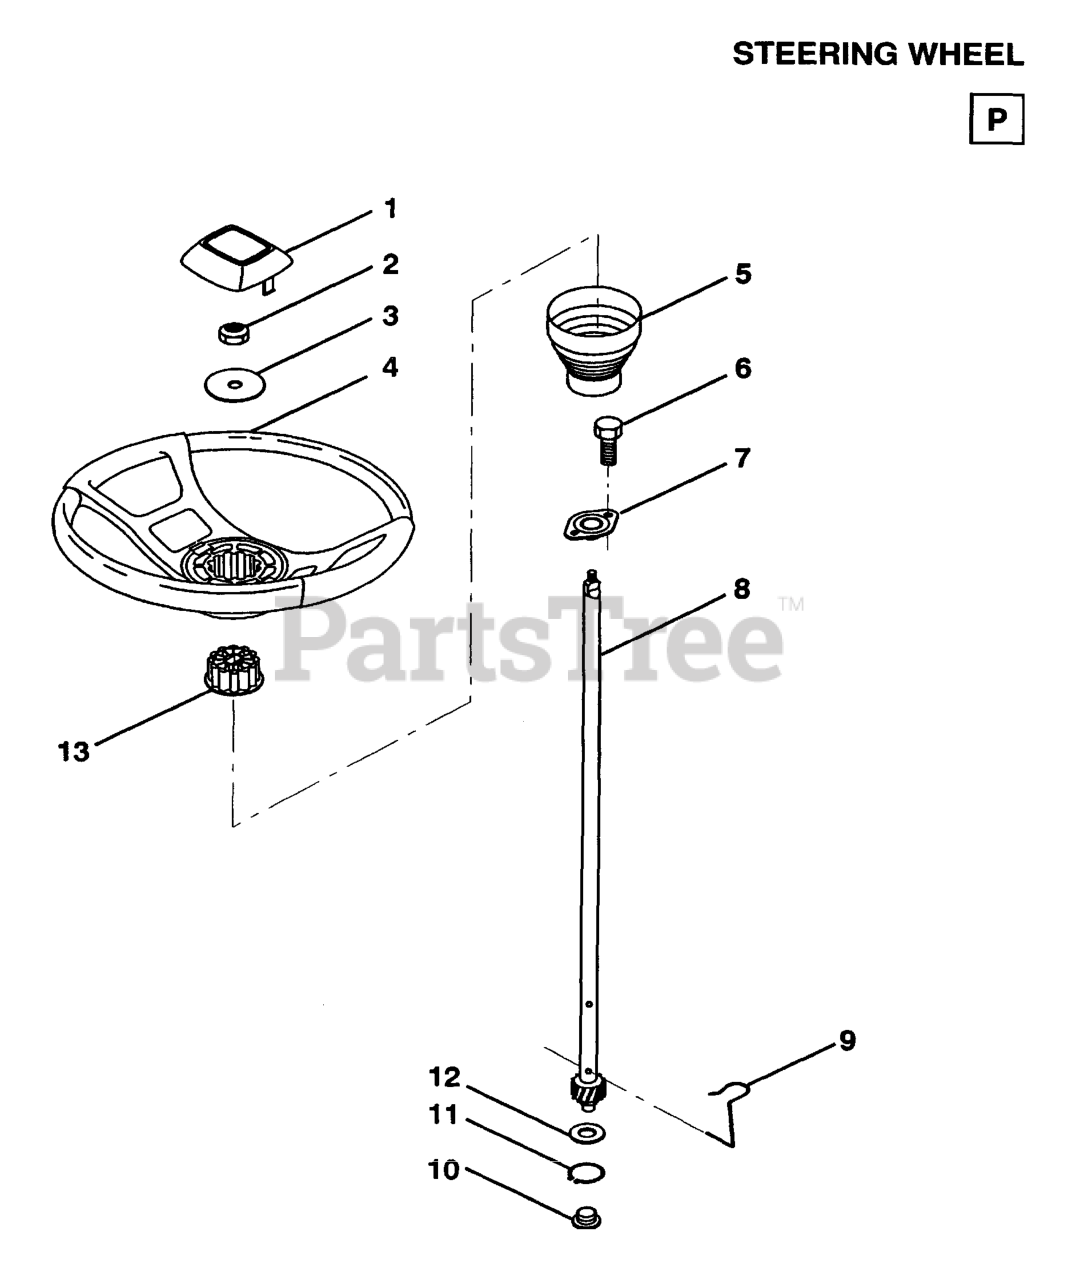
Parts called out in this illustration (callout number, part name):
1	INSERT,STR WHEEL
2	NUT
3	WASHER T
4	STEERING WHEEL
5	STEERING SLEEVE
6	Screw - Hex Washer Hd. Tapping 10 - 16 x 5/8
7	BUSHING-STRG LT
8	SHAFT STEERING
9	STEERING CLIP
10	BUSHING STEER LWR
13	ADAPTER-WHEEL LT
